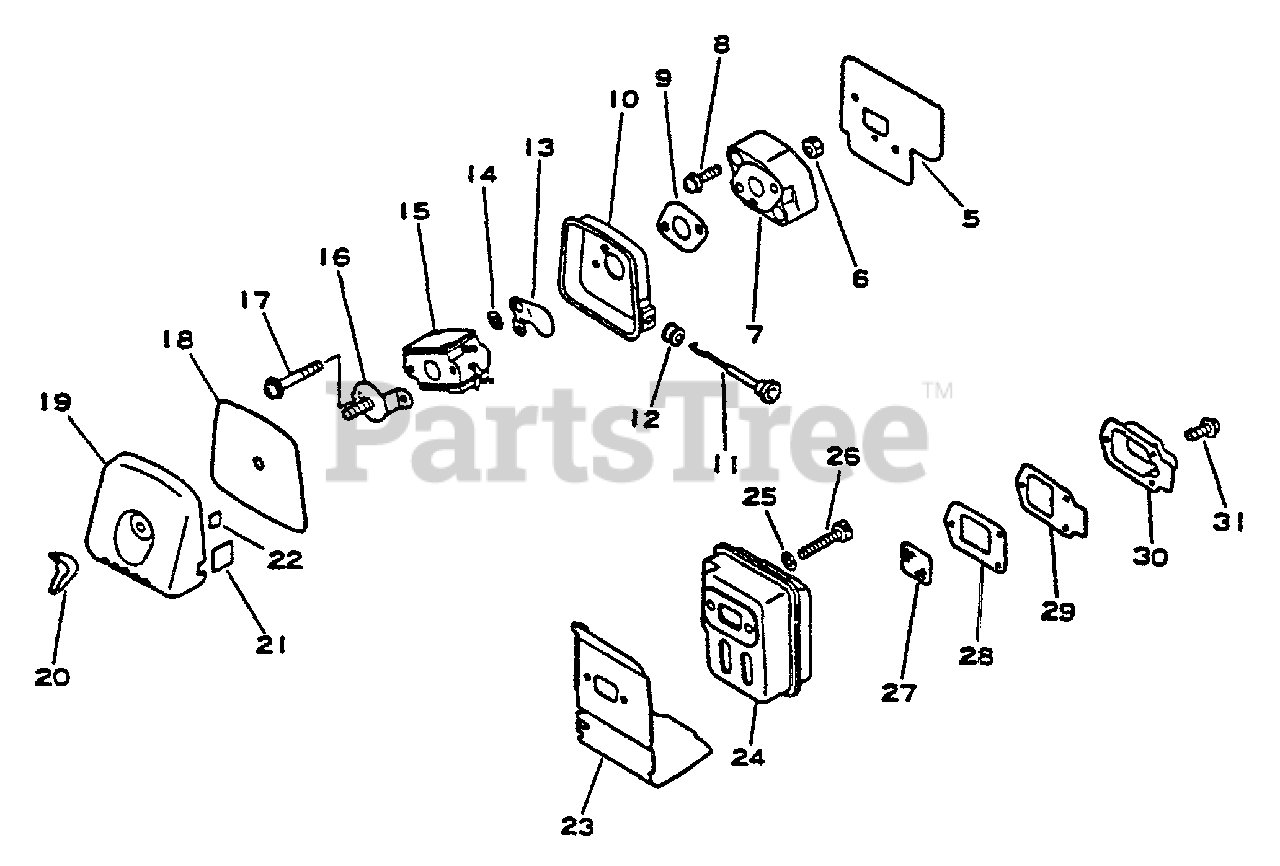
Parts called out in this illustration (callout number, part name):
5	GASKET, INTAKE
6	NUT M5
7	INSULATOR, INTAKE
8	SCREW 5×22
9	GASKET, INTAKE
10	CASE, AIR FILTER
11	ROD, CHOKE
12	GROMMET, CHOKE
13	SHUTTER, CHOKE
14	WASHER 5.2×8×0.8T
15	CARBURETOR
16	PLATE, PREVENT
17	SCREW 5×57
18	FILTER, AIR
19	COVER, AIR FILTER
20	WINGNUT - 6
21	LABEL, CAUTION
22	LABEL - CHOKE
23	COVER, MUFFLER
25	WASHER, FLAT 5.5×10×0.8
26	BOLT 5×55
27	SCREEN, SPARK ARRESTER
28	GASKET, EXHAUST
29	GUIDE, EXHAUST
30	GUIDE, EXHAUST - INNER
31	SCREW 4×10
